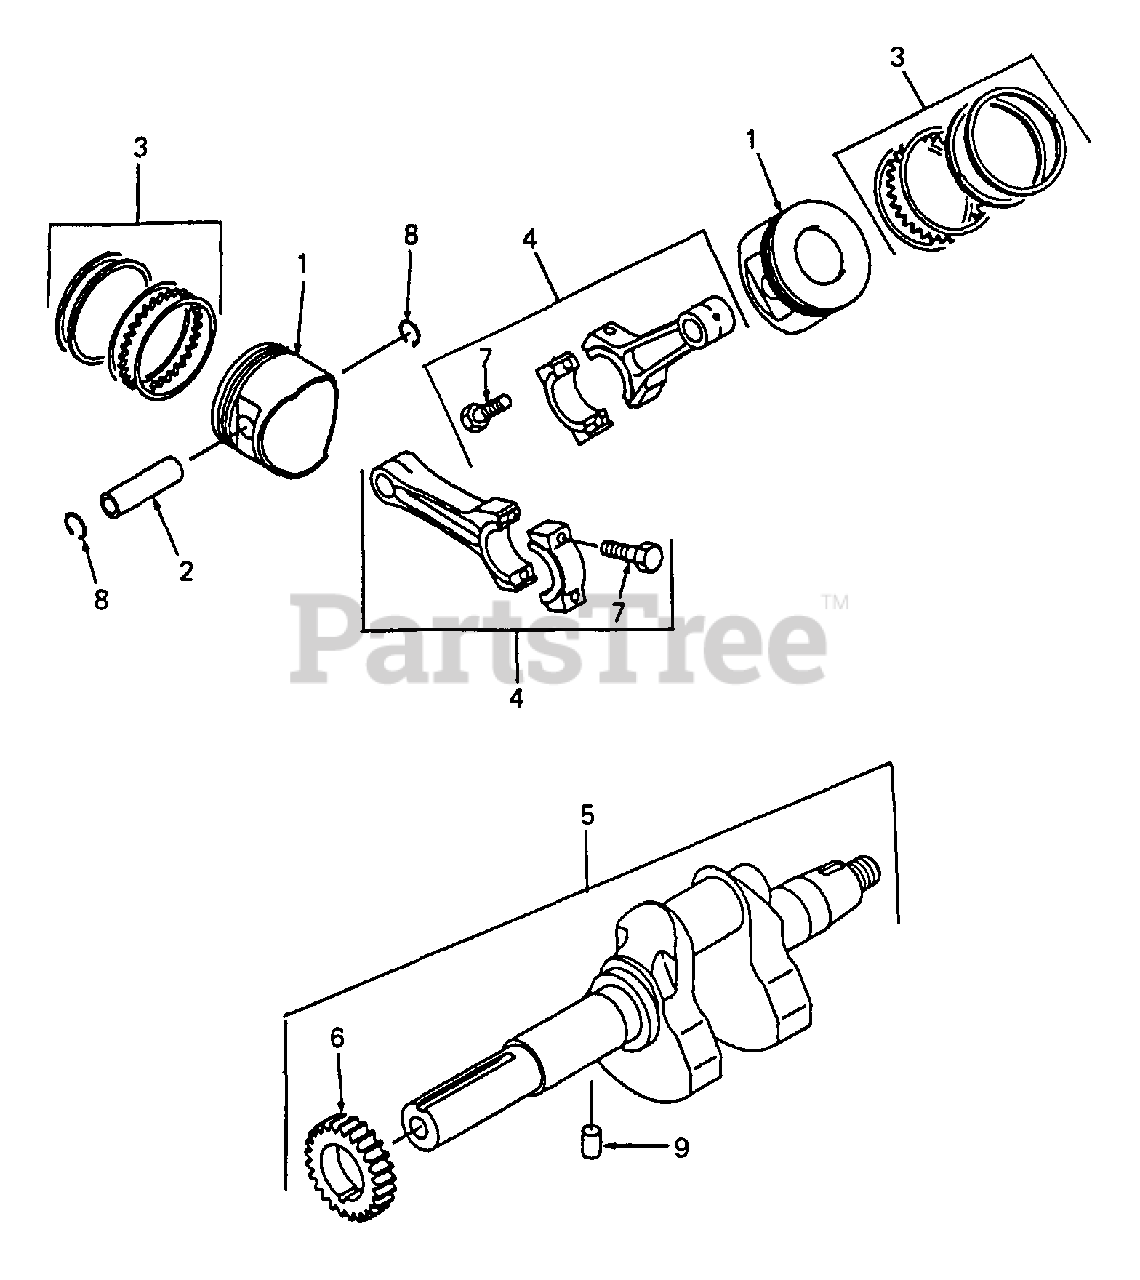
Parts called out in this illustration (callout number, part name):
3	Ring Set, Piston Std
4	Rod Assy, Connecting
5	Crankshaft Assy
7	Bolt, Conn Rod
8	Circlip, Piston Pin
